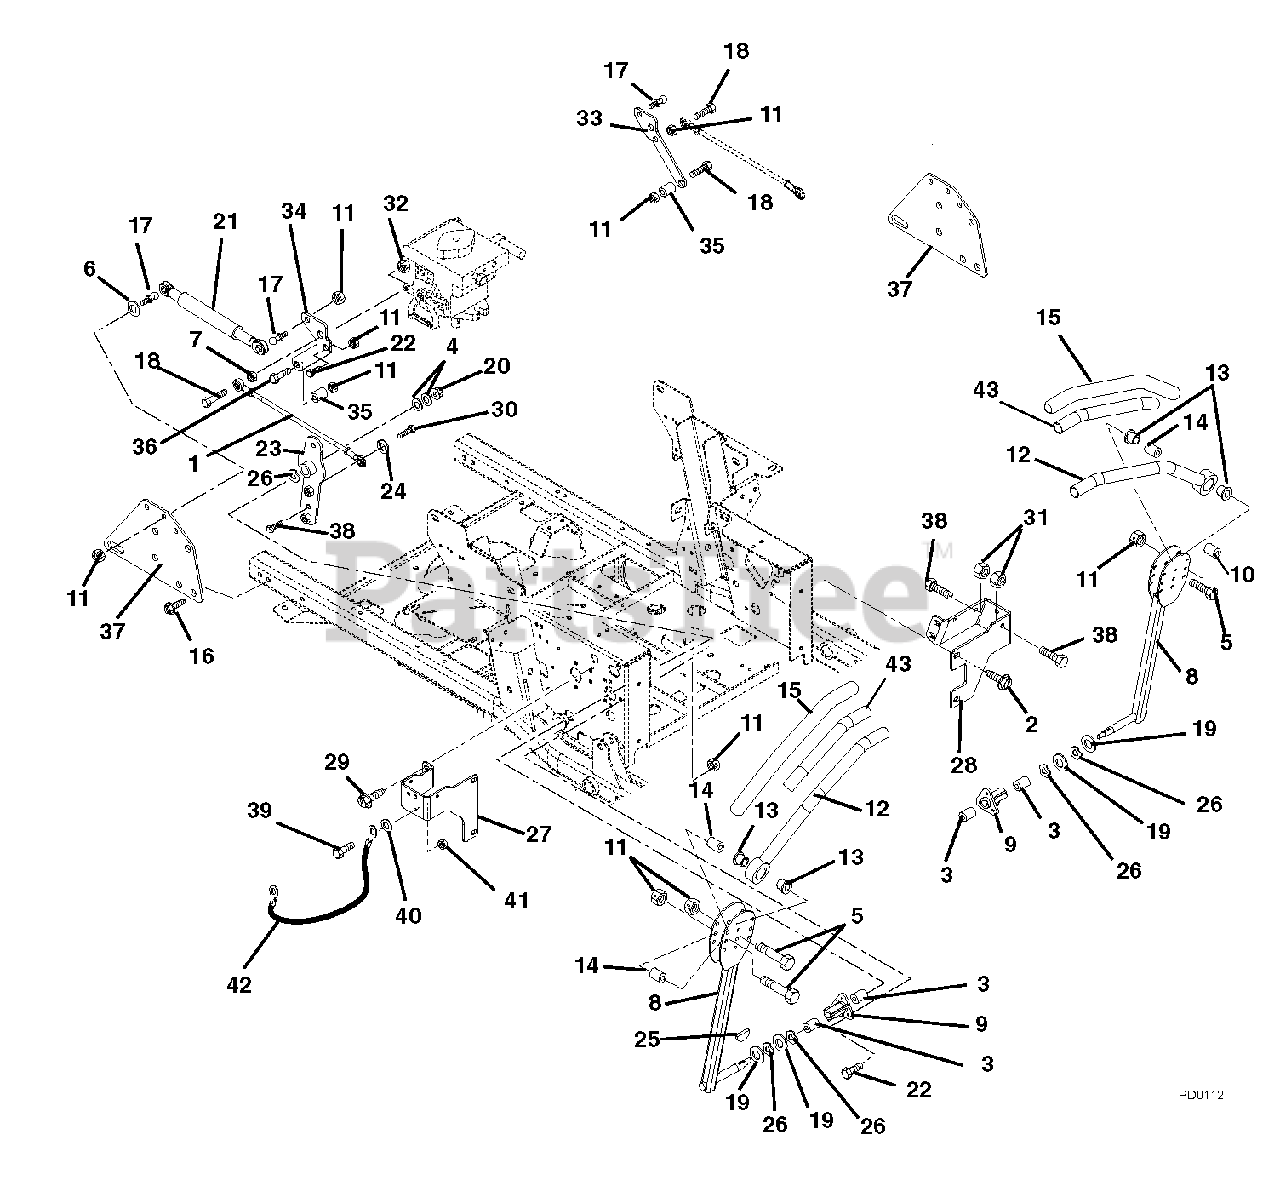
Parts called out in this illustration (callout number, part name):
1	Assembly, Steering Rod .38 Rod x 7.60
2	Screw, Tapping .38-16 x .75 Hex Washer Head
3	Bushing .625 x .75 x .50
4	Washer, Flat Steel .403 x .812 x .065
5	Bolt, Hex .31-18 x 1.75 Grade 5
6	Washer, Flat Steel .344 x .688 x .065
7	Nut, Hex .38-16
8	Control Arm
9	Bushing, Flange
10	Bushing, Eccentric .31 x .75 .97
11	Nut, Locking Top Flange .31-18
12	Handle Weldment, Left-Hand
13	Bushing, Flange Nylon .762 x 1.48 x .44
15	Grip, Handlebar
16	Screw, Tapping .31-18 x .50 Hex Washer Head
17	Stud, Ball
18	Bolt, Hex .38-16 x 1.50 Grade 5
19	Washer, Flat Steel .63 x 1.005 x .062
20	Nut, Locking Top Flange .38-16
21	Damper, Control
22	Bolt, Hex .31-18 x .75 Grade 5
23	Weldment, Pivot Arm
24	Washer, Locking .38 x .094 Regular
25	Key, Woodruff .13 x .63
26	Washer, Wave
27	Stop, Steering Right Hand
28	Stop, Steering Left Hand
29	Screw, Tapping .38-16 x .50 Hex Washer Head
30	Bolt, Hex .38-16 x 1.25 Grade 5
31	Nut, Hex Jam .375-16
32	Nut, Locking Center .38-16
33	Bracket, Left Hand
34	Bracket, Right Hand
35	Spacer .318 x .43 x .375
36	Bolt, Hex .31-18 x 1.25 Grade 5
37	Bracket, Damper
38	Bolt, Hex .375-16 x 1.75 Full Thread
39	Bolt, Hex .25-20 x .75 Grade 5
40	Washer, Flat Steel .265 x .50 x .087
41	Nut, Locking Top Flange .25-20
42	Cable, Hood
43	Tube, .88ID x 1.00OD x 10.75
